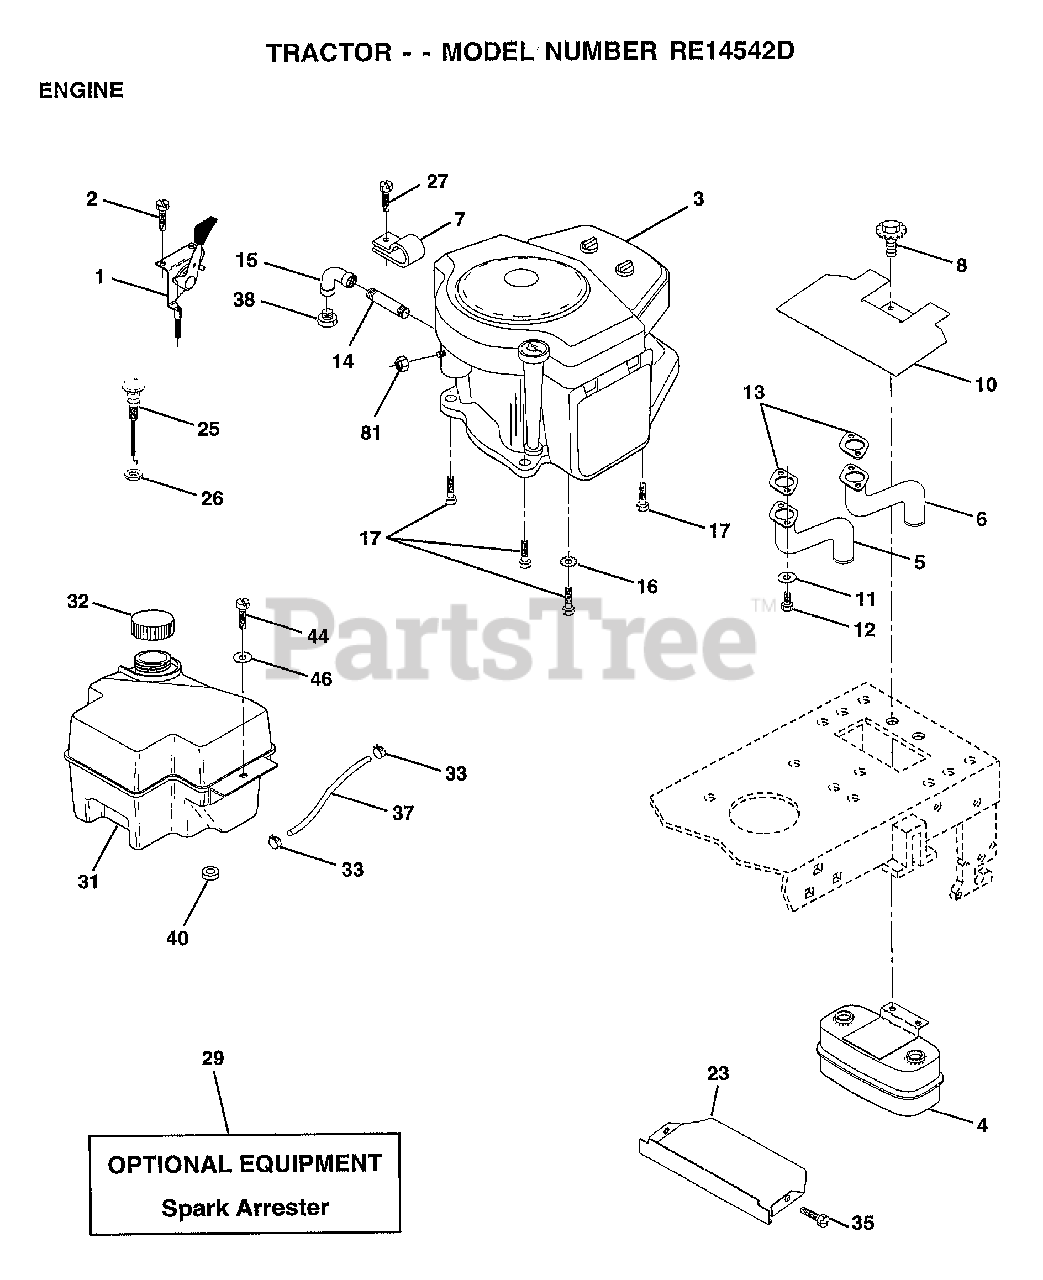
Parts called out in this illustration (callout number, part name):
1	CONTROL THRT 35.5
2	SCREW LT
4	MUFFLER.TW.LOTONE
5	EXHAUST.B&S.18.LH
6	EXHAUST.B&S.18.RH
7	CLAMP.TUBE.DBL.EN
8	BOLT.5/16-18.UNC
10	SHIELD.HEAT.
11	LOCKWASHER
13	GASKET MUFFLER
14	PIPE NIPPLE LT
15	ELBOW
16	LOCKWASHER
17	SCREW LT
23	SHIELD.BRN/DBR.GD
25	CONTROL.CHOKE.37
26	"NUT,KEPS 3/8-24IM"
27	"SCREW-TT,10-32 FL"
31	TANK.FUEL.FRONT.
32	CAP ASM FUEL
33	HOSE CLAMP
35	SCREW
37	LINE FUEL
44	SCREW HEX CRT
46	WASHER
81	NUT
